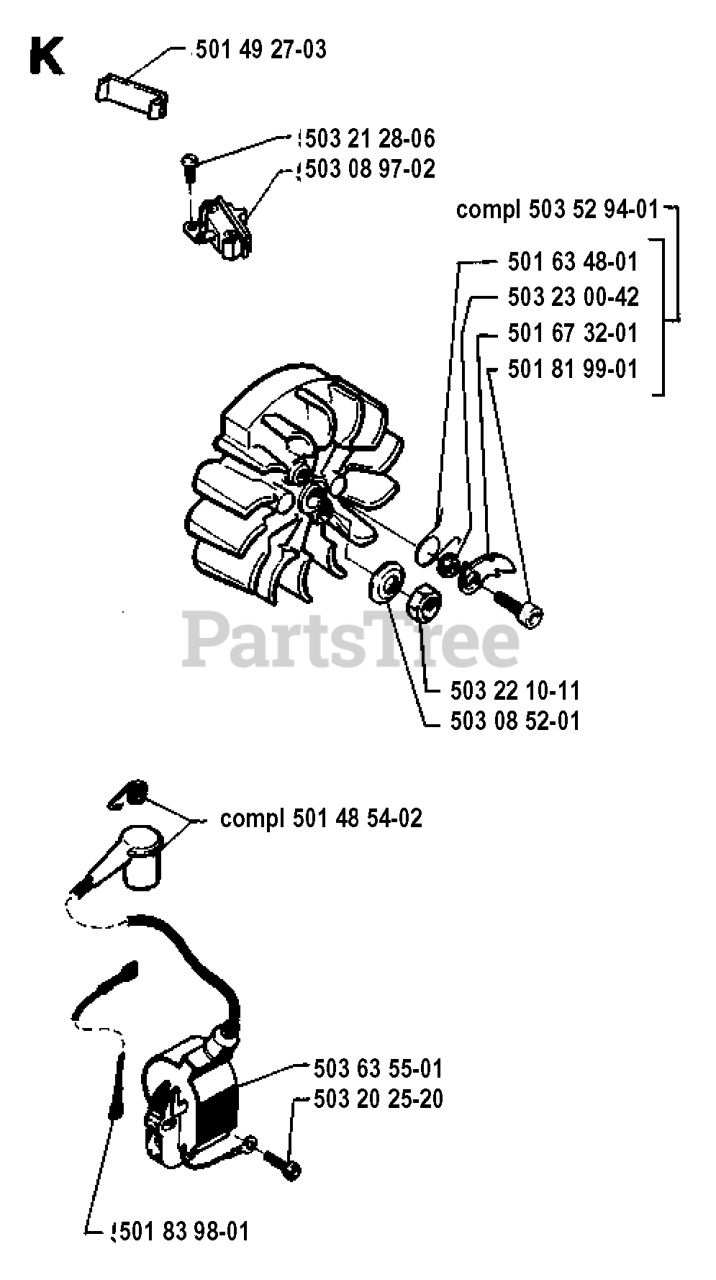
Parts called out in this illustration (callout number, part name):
2	DRAWBAR.LOWER.2PC,20"TIRES
3	RP LOGO
5	DASH ASM.HUSQ.GT.E.RDGA.N/CK.
14	HOOD
15	LENS.LH.TEX.GT.HUSQ.CL
18	GRILL.ASM.HUSQ.TG/CRD.W/TRIM
25	LENS.RH.TEX.GT.HUSQ.CL
36	SCREW 5/16"
37	FENDER.PNT.TX.GT.CH/FW.ORANGE
58	DRAWBAR.UPPER.2PC,LRG.FENDER
68	Screw 5/16-18 x 1/2 Hex, Self Tapping 5/16-18 x 1/2
130	SCREW.#10 X 0.750.BOS
137	BUMPER DASH
150	AIR.DUCT.HOOD.TEX.GT.HUSQ
152	SHIELD.BROWNING/DEBRIS
159	SCREW, 3/8-16X3/4
161	CONSOLE.FUEL.WINDOW.HU
162	SCREW.HI-LO.CONSOLE
165	SUPPORT.TANK.REAR.B/TE
175	PLATE.CROSSMEMBER.HUSQ
176	SCREW.#10-24X5/8.RN.QU
177	BUSHING, STEERING
178	CARGO.ASM.NET.TXGT.W/C
180	CHASSIS.STAMPING.LT/GT
181	BUSHING.MNT.FEND.CRGO.
182	DASH.LOWER.COMMON.12V.ADAPTOR
183	BOLT.5/16-18X1-1/4 FULL THD
189	SCREW
194	NUT LOCK HEX FLANGE 5/16-18
196	CONSOLE.ASM.DCKLFT.W/RF.HQ.DLR
199	PLATE.DECK.LIFT.HUSQVARNA.GT
202	VENT.SIDE.HOOD.HUSQ.RH.GREY
203	VENT.SIDE.HOOD.HUSQ.LH.GRAY
204	HOOD VENT
205	SKIRT.HOOD.SIDE.HUSQ.RH.GREY
206	SKIRT.HOOD.SIDE.HUSQ.LH.GREY
207	BEZEL.RH.TEX.GT.HUSQ
208	BEZEL.LH.TEX.GT.HUSQ
209	INSERT.HEX.GRILL.HUSQ.GREY
210	INSERT.HEX.GRILL.HUSQ.
211	INSERT.HEX.GRILL.HUSQ.
212	INSERT.HEX.GRILL.HUSQ.
214	CLIP.RETAINER.TINNER.
217	ROD.PIVOT.HOOD
221	REFLECTOR.LH.TEX GT HU
228	STUD.FASTNER.W/ANTI-ROTATE
233	BOLT.SHOULDER
234	BUMPER.HOOD.TEX.HUSQVARNA
235	SPACER FENDER
236	NUT.CENTERLOCK.5/16-
238	TRIM.HUSQ.TG/CRD.SERVICE
298	NUT PUSH M
